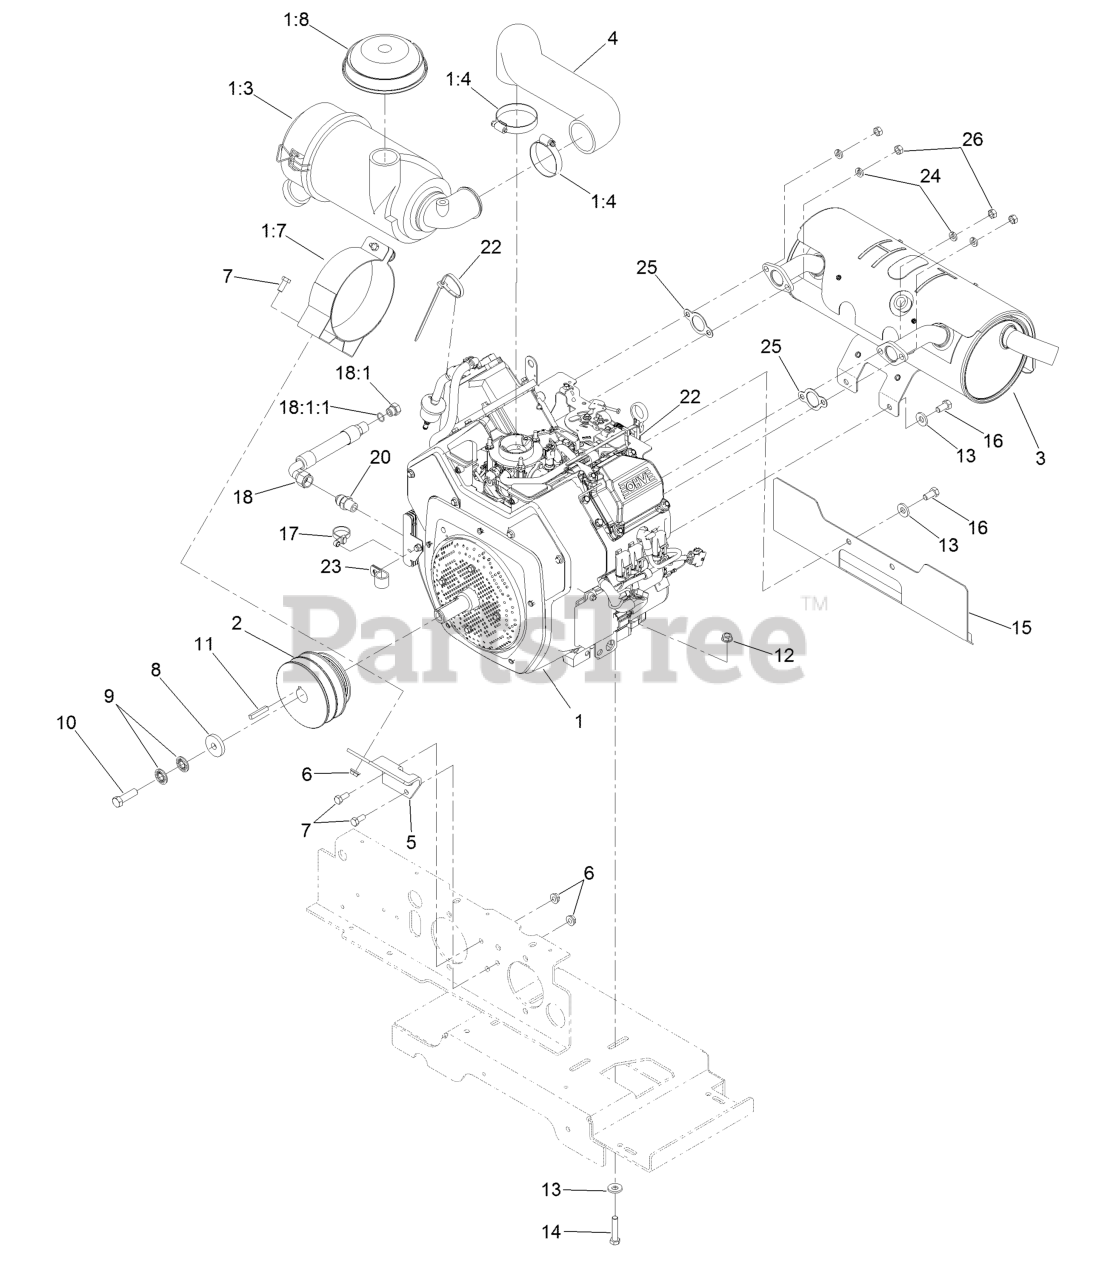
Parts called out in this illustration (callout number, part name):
1:3	Air Cleaner Canister ASM
1:4	Clamp-Hose
1:7	Bracket-Filter, Air
1:8	Hood-Cleaner, 2" Air Intake
2	Sheave-Engine
3	Muffler
4	Hose-Air Intake
5	Bracket-Filter, Air
7	Screw-HH
8	Washer-Clutch
9	Washer-Spring
10	Screw-HH
11	Key-Square
12	Nut-HHF, Whiz
13	Washer-Belleville
14	Screw-HH
15	Shield-Exhaust
16	Screw-HH
17	Tie-Cable
18	Oil Drain Hose ASM
18:1	Plug-HH
18:1:1	O-Ring
20	Fitting-Straight
22	Tie-Plastic
23	Clip-Loom
24	Washer-Lock
25	Gasket-Exhaust
26	Nut-Hex
